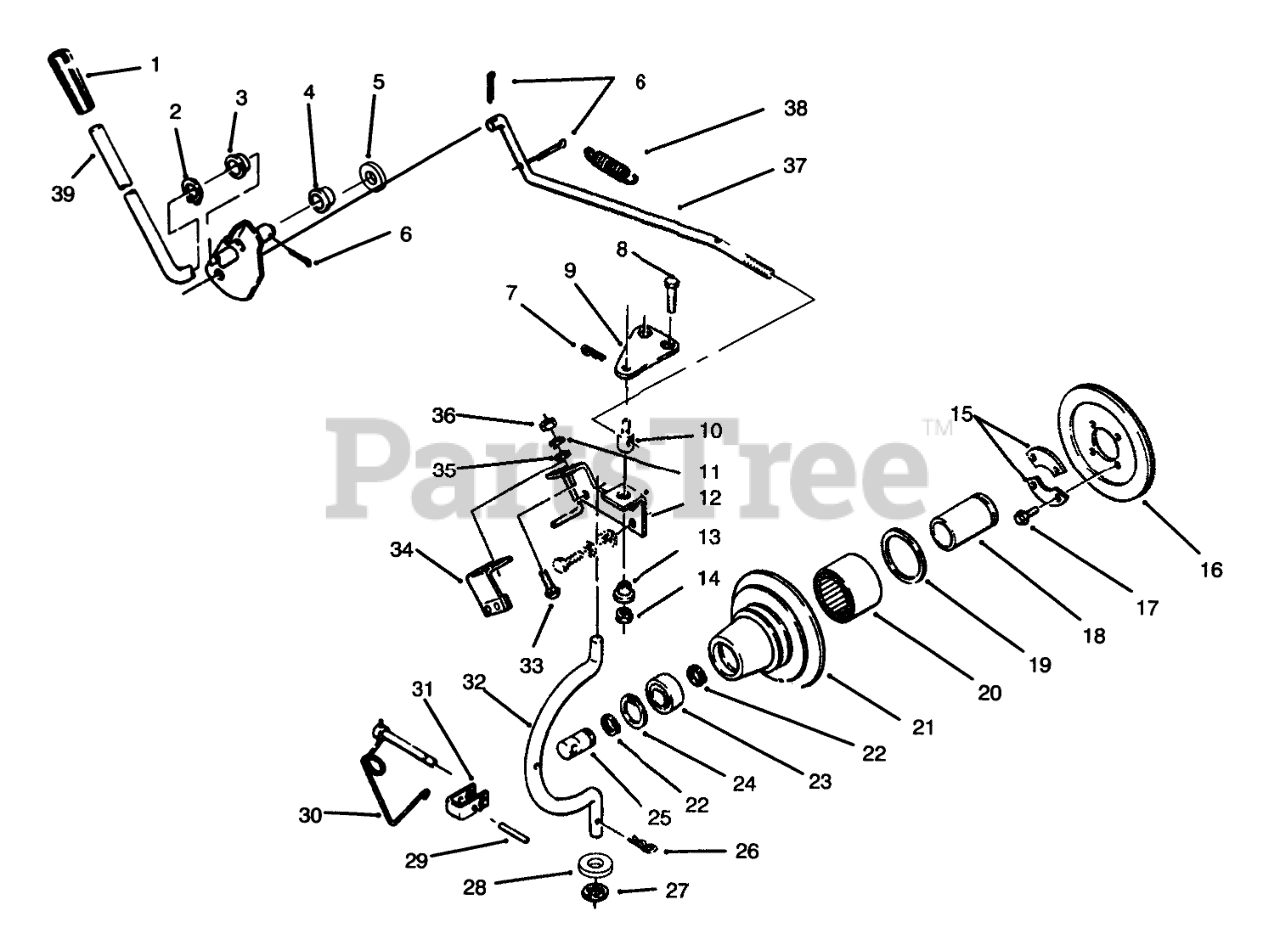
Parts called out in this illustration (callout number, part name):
1	GRIP
2	RING-EXT GRIP
3	BUSHING-NYLINER
4	NYLINER BUSHING
5	SHIM-WASHER
6	PIN-COTTER
7	Hairpin Cotter
8	SCREW-HH
9	PLATE
10	TRUNNION
11	WASHER-LOCK
12	Bracket-Engine
13	SPACER-LIFT LINK
14	NUT-LOCK, NI
15	RETAINER
16	Facing-Clutch
17	H H C S
18	RACE-BEARING
19	SEAL-OIL
20	Seal
21	Housing-Clutch
22	Ring-Snap
23	BEARING-BALL
24	RING-RETAINING
25	SHAFT-PTO
26	Hairpin
27	RING-REINFORCED CIRC
28	WASHER-FLAT
30	LOCKING PIN ASM
31	CLEVIS
32	ROD-HOUSING
33	SCREW-CARR
34	ASM-Bracket
35	WASHER-FLAT
36	NUT-JAM
37	ROD-PTO CLUTCH
38	SPRING
39	Lever-Clutch,PTO
